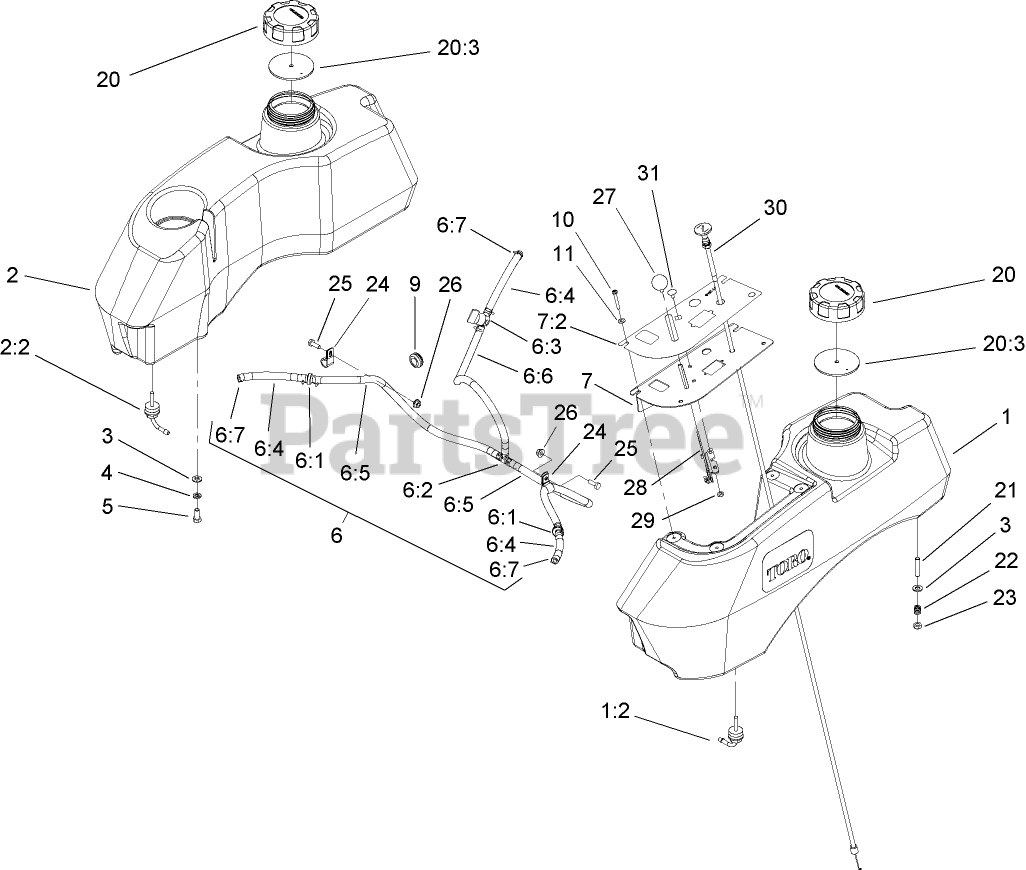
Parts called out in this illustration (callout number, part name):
1	LH FUEL TANK ASM
1:2	FITTING-FUEL, BULKHEAD
2	RH Fuel Tank ASM
2:2	FITTING-FUEL, BULKHEAD
3	WASHER-PLAIN
4	WASHER-LOCK
5	SCREW-HH
6	FUEL LINE ASM
6:1	VALVE-CHECK, FUEL
6:2	FITTING-TEE, BARBED
6:3	VALVE-FUEL
6:4	HOSE-FUEL
6:5	HOSE-FUEL
6:6	HOSE-FUEL
7	CONTROL PANEL ASM
7:2	DECAL-PANEL, CONTROL
9	GROMMET
11	WASHER-SPRING
20	GAS CAP ASM
20:3	GASKET-CAP, GAS
22	SPRING-TANK, FUEL
23	NUT-LOCK, NI
24	CLIP-LOOM
25	SCREW-HH
26	NUT-HF
27	KNOB-BALL
28	THROTTLE CABLE ASM
29	NUT-LOCK, NI
30	CONTROL-CHOKE
31	BOLT-CARR
